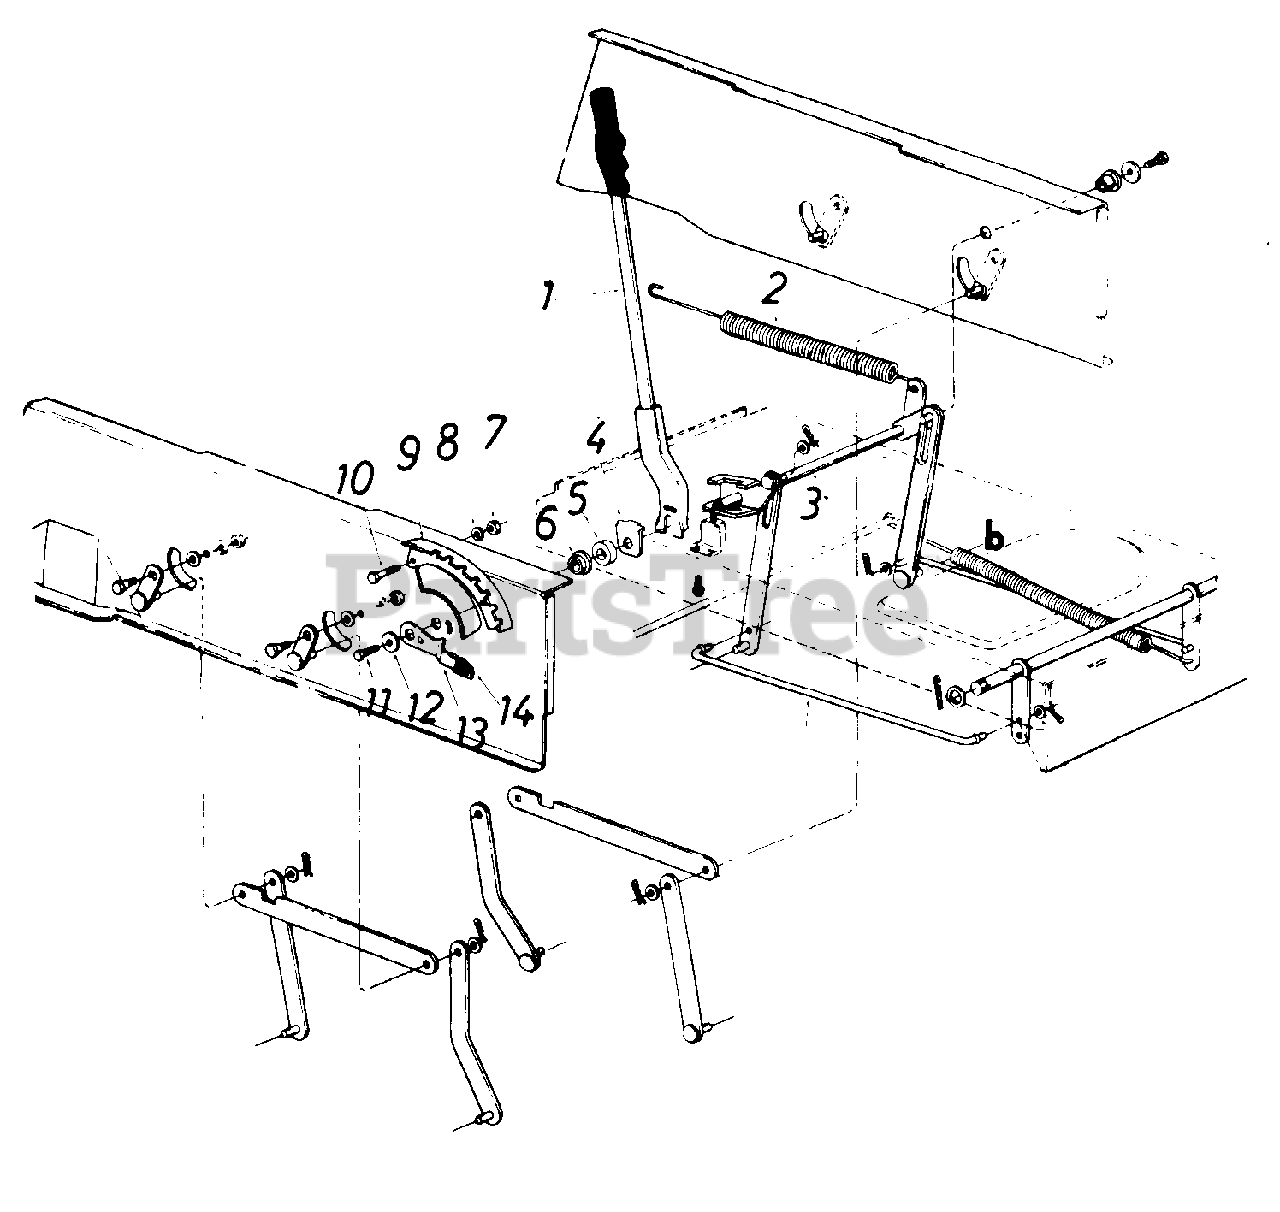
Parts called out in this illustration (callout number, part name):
1	Lift Handle Ass'y.
2	Extension Spring .99" O.D. x 11" Lg.
5	Rubber Wash. 1.50" O.D. x .63" I.D.
6	Flange Wash. .628" I.D. x 1.25" O.D.
7	Hex Nut 5/16-18 Thd.
8	L.-Wash. 5/16" I.D
9	Index Bracket
10	Hex Bolt 5/16-18 x .75" Lg.
11	Hex Wash. Hd. Self-Tap Scr. 5/16-18 x .62" Lg.
12	Fl.-Wash. .344" I.D. x 1.25" Lg.
13	Deck Lift Down Stop
14	Knob
